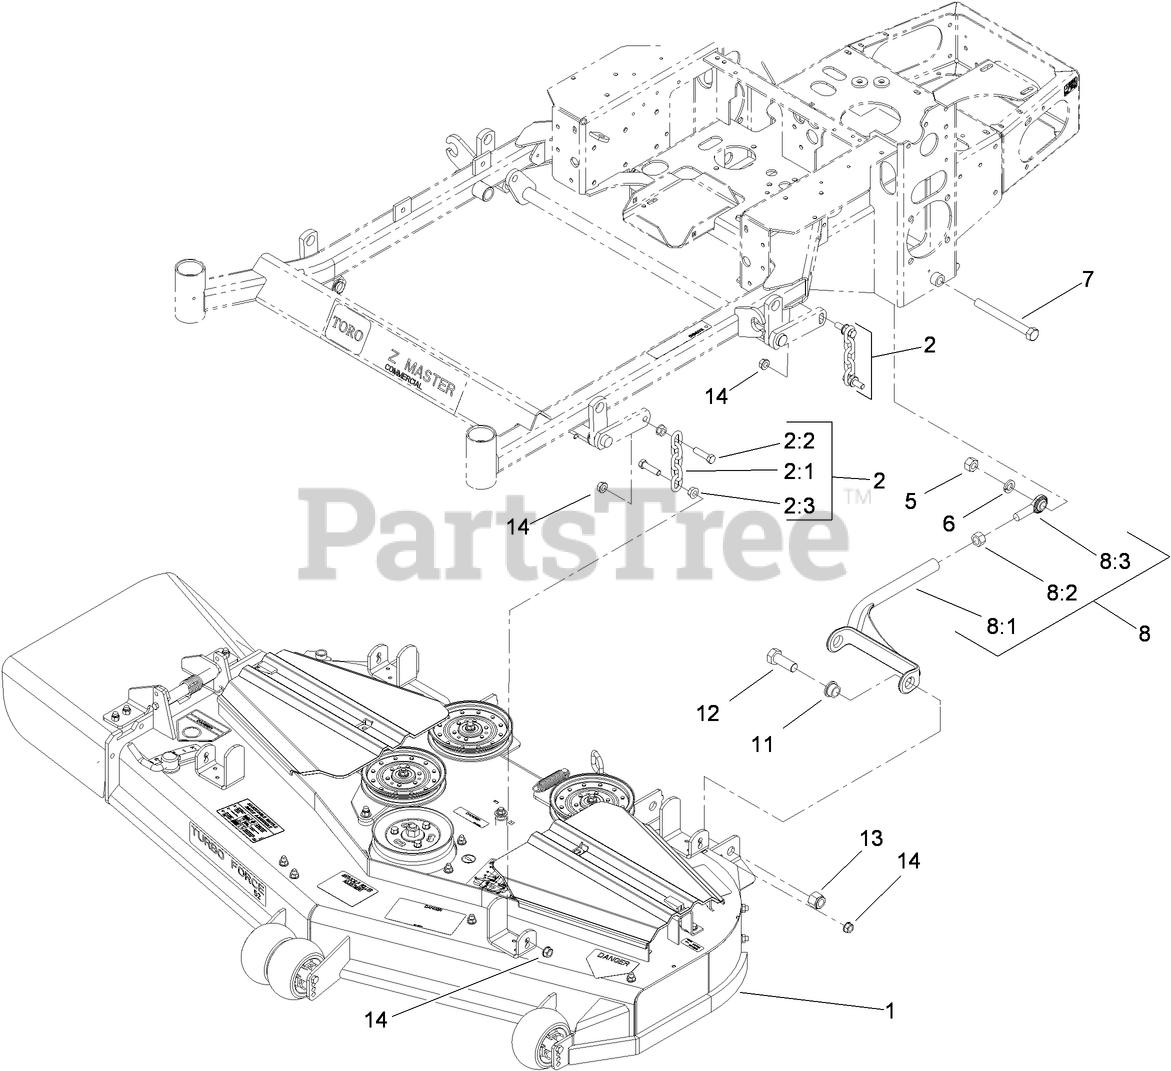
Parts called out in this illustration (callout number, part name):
1	DECK ASM
2	DECK CHAIN ASM
2:1	CHAIN-LIFT, DECK
2:2	SCREW-HH
2:3	NUT-HF
5	NUT-HEX
6	WASHER-LOCK
8	STRUT ASM
8:1	STRUT-DECK
8:2	NUT-HEX
8:3	BALLJOINT-SPHERICAL
11	BUSHING
12	SCREW-HH
13	NUT-LOCK, NI
14	NUT-HF
